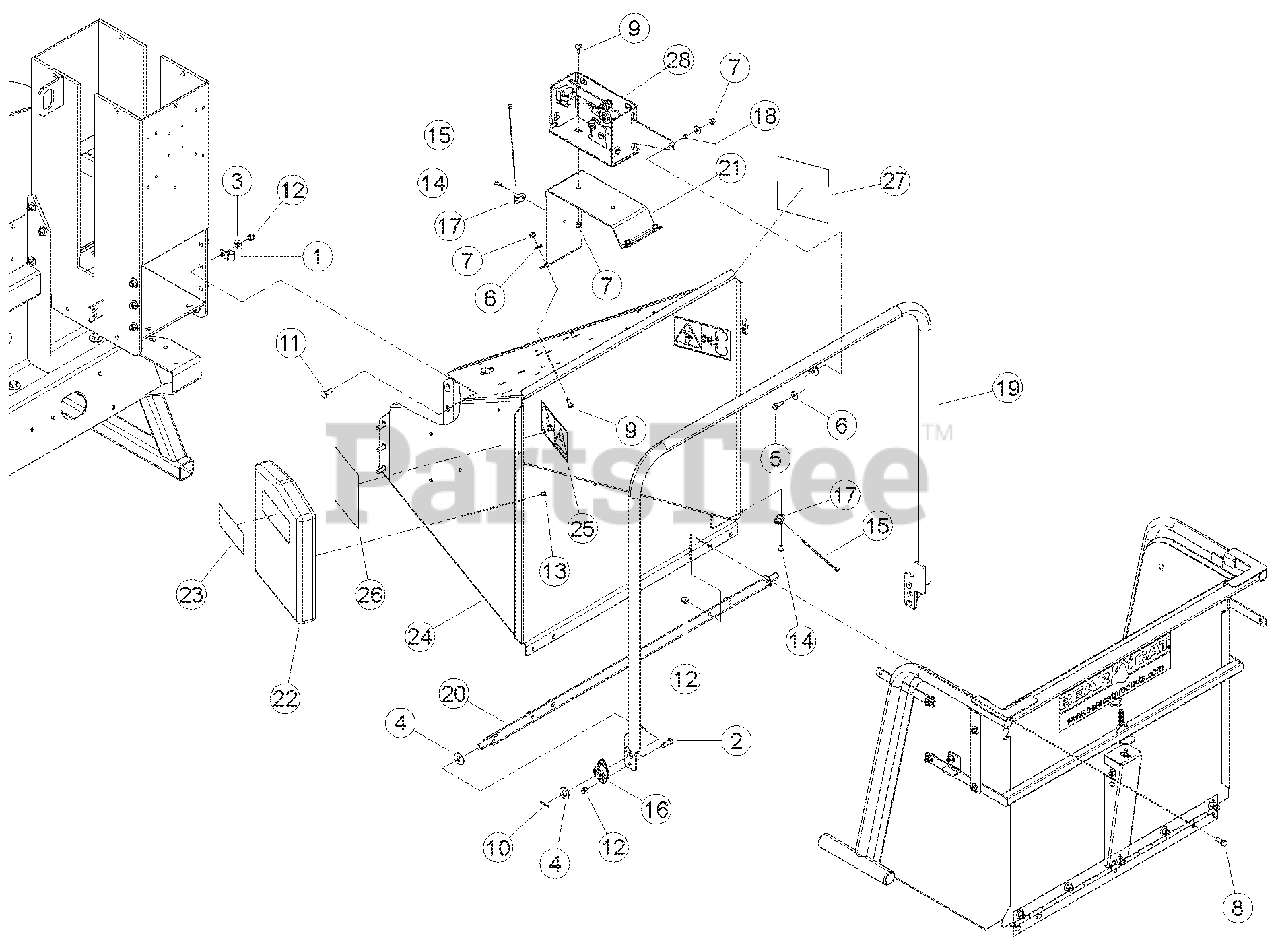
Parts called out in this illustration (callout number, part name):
1	CLAMP, 9/16" COATED
2	BOLT, 3/8 X 1 HEX HD GR5 ZP
3	WASHER, 3/8 FLAT ZP
4	WASHER, 5/8 SAE FLAT ZP
5	BOLT, 5/16 X 1 HEX HD GR5 NC ZP
6	WASHER, 5/16 FLAT ZP
7	NUT, 5/16 NE NYLOCK ZP
8	BOLT, 3/8 X 1-1/4 HEX HD GR5 ZP
9	BOLT, 5/16 X 3/4 CRG GR5 NC ZP
10	PIN, 1/8 X 1.00 ZP COTTER
11	BOLT, 3/8 X 1-1/4 CRG GR5 NC ZP
12	NUT, 3/8 NE NYLOCK ZP
13	RIVET, AL BLIND 1/4 X 1/2 DOME HEAD
14	RIVET, AL BLIND 1/4 X 3/4 DOME HEAD
15	STRAP, 11 IN. BLACK TIE
16	BEARING, SIDE FLANGE MOUNT 5/8"
17	CLAMP, CABLE MOUNT
18	SPACER, IDLER PIVOT
19	WELDMENT, CONTROL ARM
20	WELDMENT, CONTROL PIVOT
21	MOUNT, SWITCH BOX
22	ASSEMBLY, MANUAL CONTAINER SERVICE PART (INCLUDES ITEM 23)
23	DECAL, MUTILINGUAL MANUAL
24	ASSEMBLY, BIG CHIPPER CHUTE SERVICE PART (INCLUDES ITEMS 25 - 27)
25	DECAL, BLADE DANGER ISO
26	DECAL, FEED POSITION
27	DECAL, FEED POSITION
28	ASSEMBLY, SWITCH BOX
